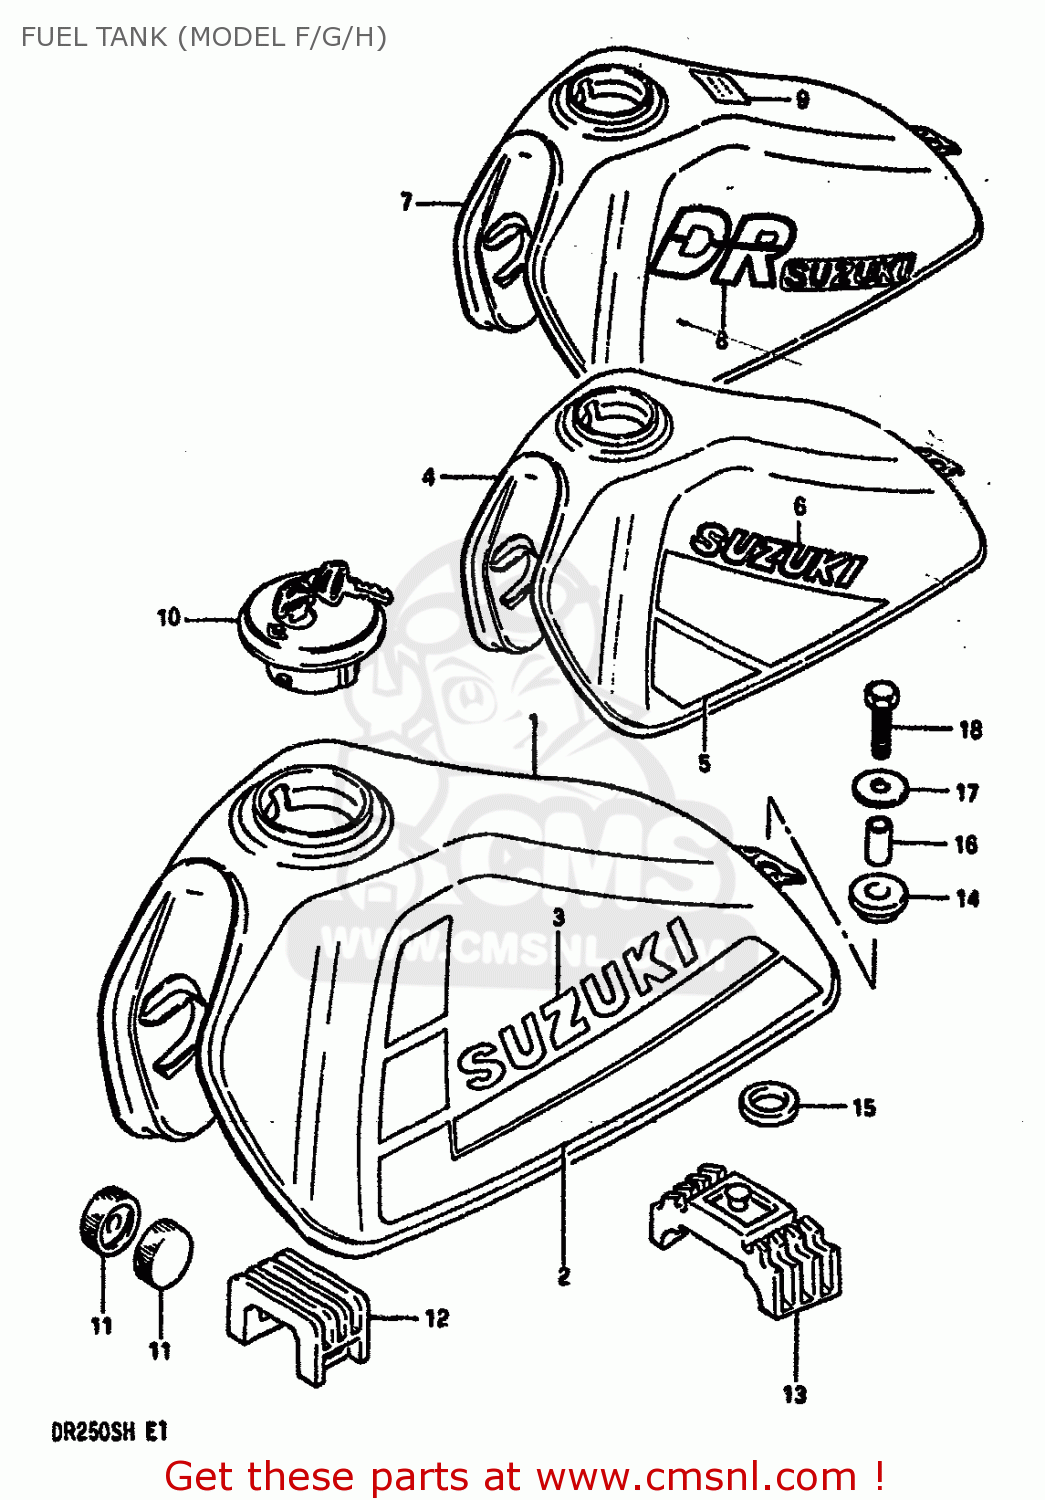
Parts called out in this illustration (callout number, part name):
1	TANK ASSY,FUEL (RED)
2	TAPE SET,FUEL TANK
3	EMBLEM
4	TANK ASSY,FUEL (RED)
5	TAPE SET,FUEL TANK
6	EMBLEM,FUEL TANK
7	TANK ASSY,FUEL (WHITE)
8	TAPE SET,FUEL TANK
9	LABEL,FUEL CAUTION
10	CAP SET,FUEL TANK
11	CUSHION
12	CUSHION,TANK UPR FR
13	CUSHION,FUEL TANK,REAR
14	CUSHION
15	CUSHION
16	SPACER(8.5X12X19)
17	WASHER (8.5X29X1.6)
18	BOLT
